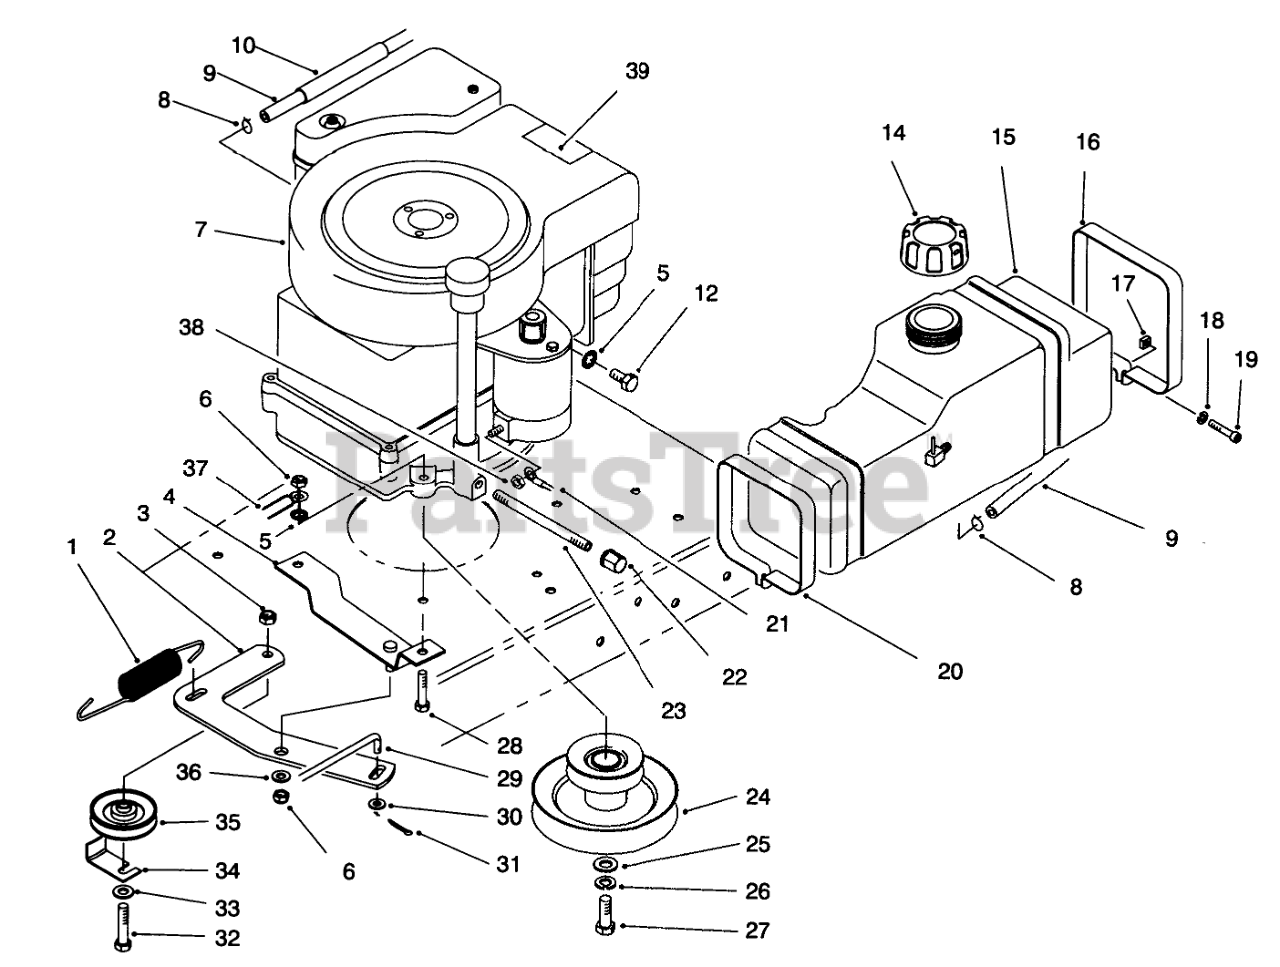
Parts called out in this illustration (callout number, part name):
1	SPRING-TRACTION
2	Plate-Mounting, Idler
3	NUT-LOCK, NI
4	Bracket W.A.-Traction
5	WASHER-LOCK, INTERNAL
6	NUT-LOCK, NI
7	Engine-11.5 H.P.
8	CLAMP-HOSE
9	HOSE - FUEL
10	SUPPORT-FUEL LINE
12	SCREW-HWHTF
14	GAS CAP ASM
15	TANK-5 QT GAS
16	Retainer-Front
17	NUT-SQUARE
18	WASHER-LOCK
19	SCREW-HSH
20	Retainer-Rear
21	WIRE ASM
22	CAP-PIPE
23	NIPPLE
24	PULLEY-ENGINE
25	WASHER-FLAT
26	WASHER-LOCK
27	SCREW-HH
28	SCREW-HH
29	ROD-TRACTION
30	WASHER-FLAT
31	PIN-COTTER
32	SCREW-HH
33	WASHER-FLAT
34	RETAINER-BELT
35	PULLEY-IDLER
36	WASHER-FLAT
37	WIRE ASM
38	NUT-JAM
39	DECAL - ENGINE 11.5 HP
